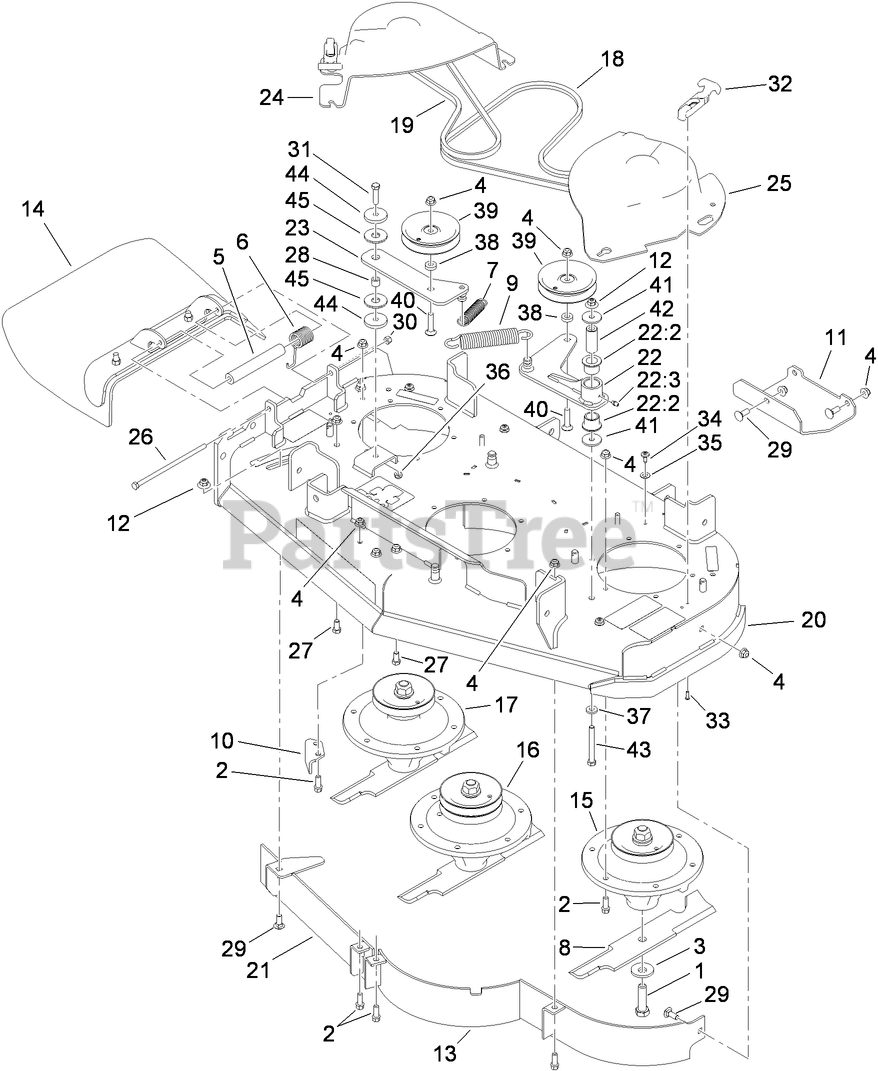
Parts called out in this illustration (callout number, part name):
1	SCREW-BLADE
2	SCREW-HWH
3	Washer-Blade Bolt, Heavy
4	NUT-HF, NI
5	SPACER
6	SPRING-TORSION
7	SPRING-EXTENSION
8	BLADE-14 INCH (HIGH SAIL)
9	SPRING-EXTENSION
10	BAFFLE-DISCHARGE
11	PLATE-SKID
12	NUT-FLANGE, NI
13	BAFFLE ASM
14	DEFLECTOR ASM
15	SPINDLE ASM
16	SPINDLE ASM
17	SPINDLE ASM
18	BELT-V
19	BELT-V
20	DECK ASM
21	FRONT BAFFLE ASM
22	IDLER ARM ASM
22:2	BUSHING
22:3	FITTING-GREASE
23	IDLER ARM ASM
24	COVER-BELT, RH
25	COVER-BELT, LH
26	SCREW-HH
27	SCREW-HH
28	BUSHING-LEVER, LIFT
29	BOLT-CARR
30	NUT-LOCK, NI
31	SCREW-HH
32	LATCH-RUBBER
33	SCREW-HSBH
34	SCREW-SHOULDER
35	WASHER-THRUST
36	NUT-LOCK, NI
37	SPACER
38	SPACER
39	PULLEY-IDLER
40	SCREW-CARR
41	WASHER
42	SPACER-PLAIN
43	SCREW-HH
44	WASHER-PLAIN
45	WASHER-FRICTION, COMPOSITE
